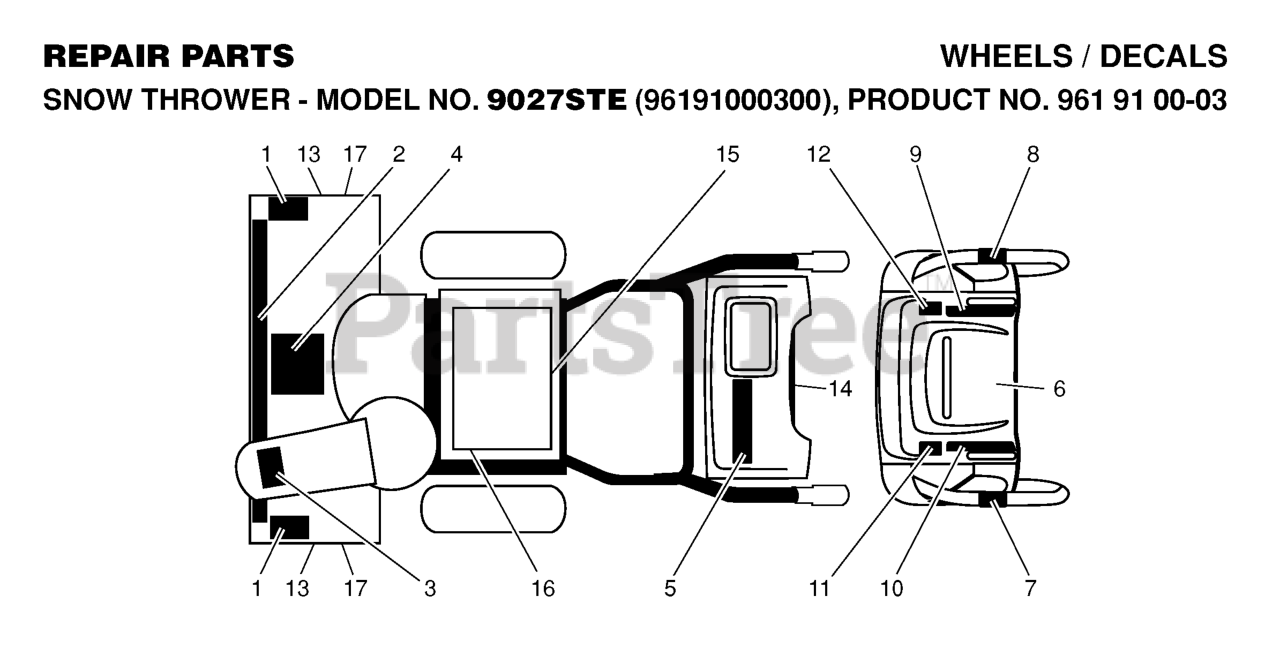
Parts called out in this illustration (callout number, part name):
4	DECAL.AUGER."
6	DECAL.CONSOLE.INSTRUCTION
10	DECAL.REM.DEFLECTOR.LT
11	DECAL, LH TRIGGER
12	DECAL, RH TRIGGER
14	DECAL.FENDER
15	DECAL.BELT.GUARD.
17	DECAL, HUSQVARNA
